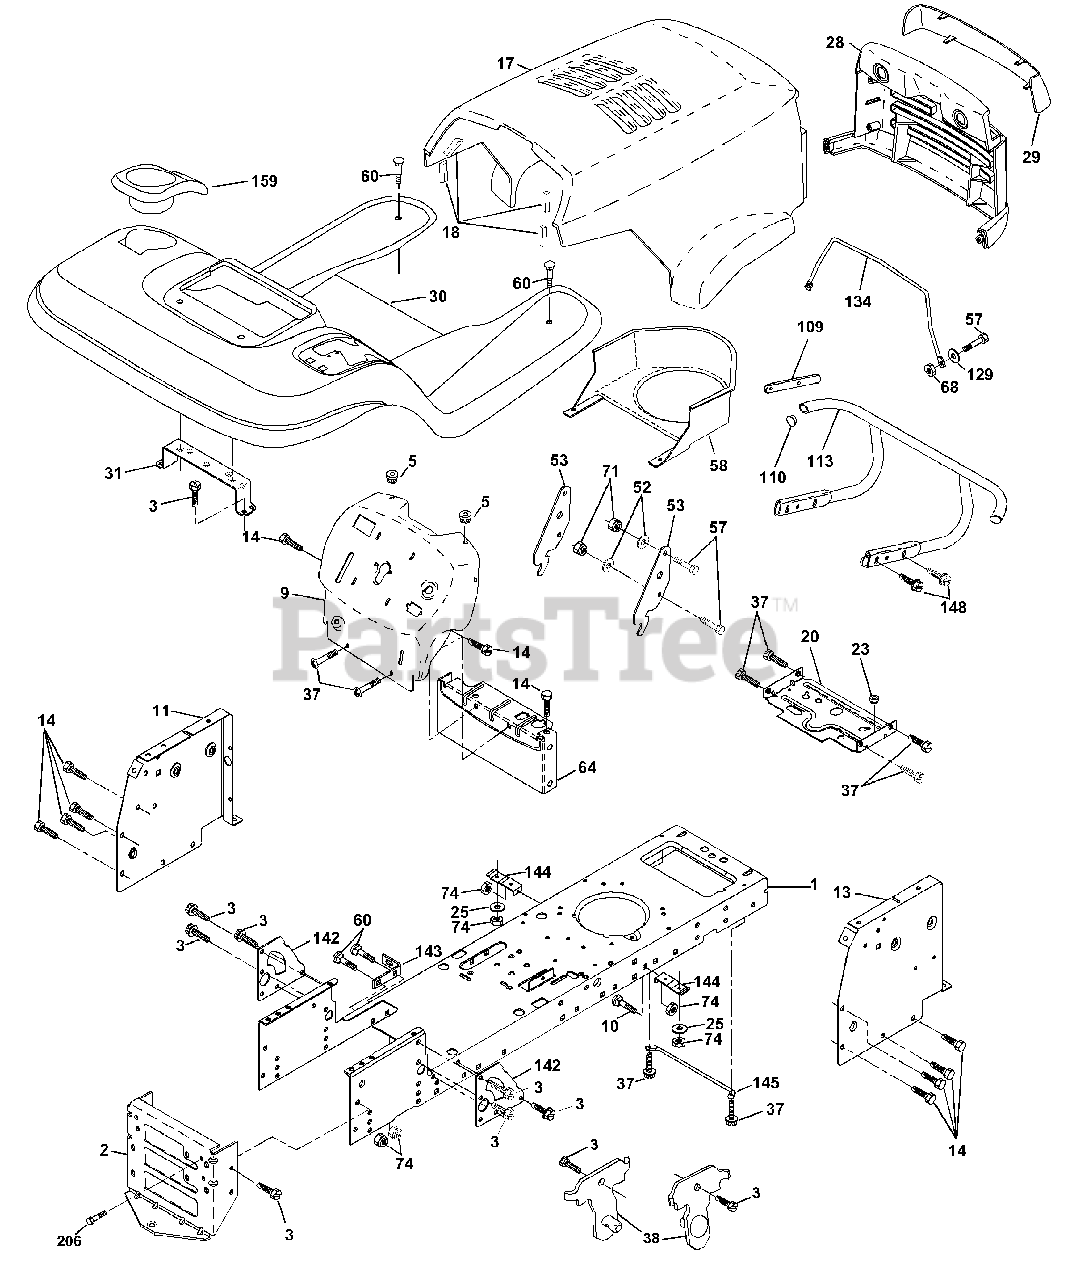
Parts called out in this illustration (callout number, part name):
1	Chassis stamping
2	Drawbar, 12 Ga.
3	Screw 3/8-16 x 3/4
5	Bumper Hood/Dash
9	Dash Slkscr
10	Bolt Carriage 3/8-16 x 1
11	Panel Dash Lh
13	Panel Dash Rh
14	Screw Thdrol 3/8-16 x 1/2 Ty-tt
17	Hood LT/PL Husqvarna
18	Bumper Hood
20	Plate Mtg Battery Fuel Tank Fr
25	Washer 13/32 X 13/16 X 12 Ga
28	Grille LT/PL Husqvarna
29	Lens LT/PL Husqvarna
30	Fender Footrest STLT Pnt
31	Bracket Support Fender
37	Screw Thdrol 6/16-18 x 1/2 TYT
38	Bracket Asm Pivot Mower Rear
52	Washer 9/32 x 7/8 x 16 Ga.
53	Bracket Pnt. Pick off LT/PL Husqvarna
57	Bolt Hex 1/4-20 x 3/4
58	Air Duct Engine P/L
60	Bolt Rdhd Sqnk 3/8-16unc x 3/4
64	Dash Lower STLT
68	Nut Keps Hex 1/4-20unc
71	Nut Crown Lock 1/4-20 Unc
74	Nut Crownlock 3/8-16 UNC
109	Bracket Extension Bumper
110	Plug Plastic
113	Bumper Asm.
129	Washer 9/32 x 5/8 x 16 Ga.
134	Rod Support Hood LT/PL Husq.
142	Plate Reinforcement STLT
143	Bracket Swaybar Chassis
144	Bracket Pnt Footrest STLT
145	Rod Pivot Chassis/Hood
148	Screw 3/8-16 x 1-1/4
159	Cupholder Stlt Grey
206	Bolt Shoulder 5/16-18 TT
